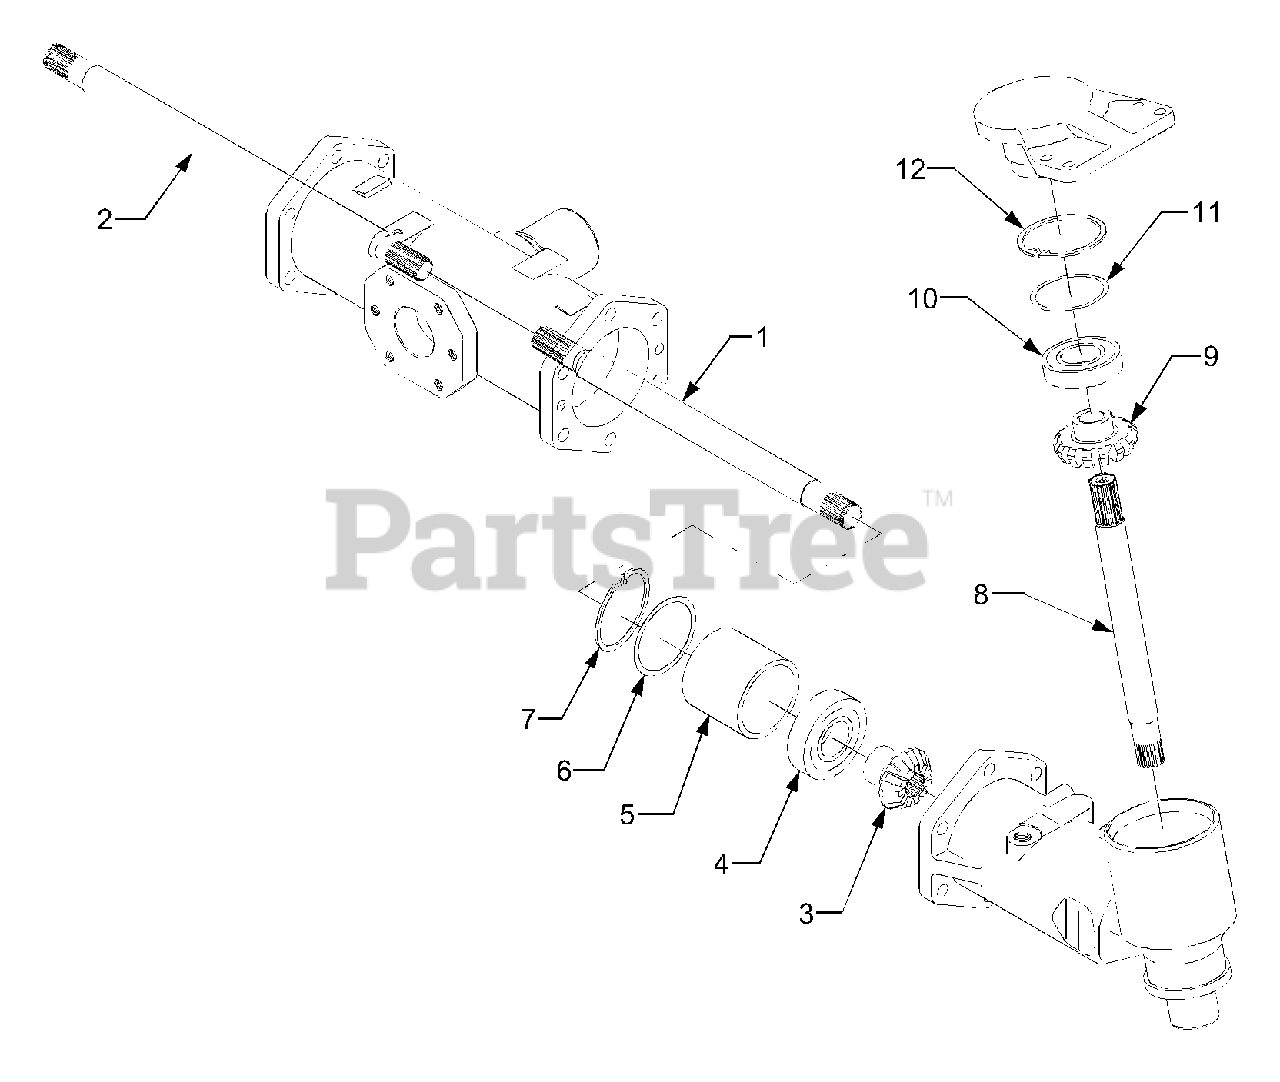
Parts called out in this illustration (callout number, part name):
1	Shaft, Differential Gear (LH)
2	Shaft, Differential Gear (RH)
3	Gear, 11 Bevel
4	Bearing, Ball
8	Shaft, Bevel Gear
9	Gear, 16 Bevel
10	Bearing, Ball
